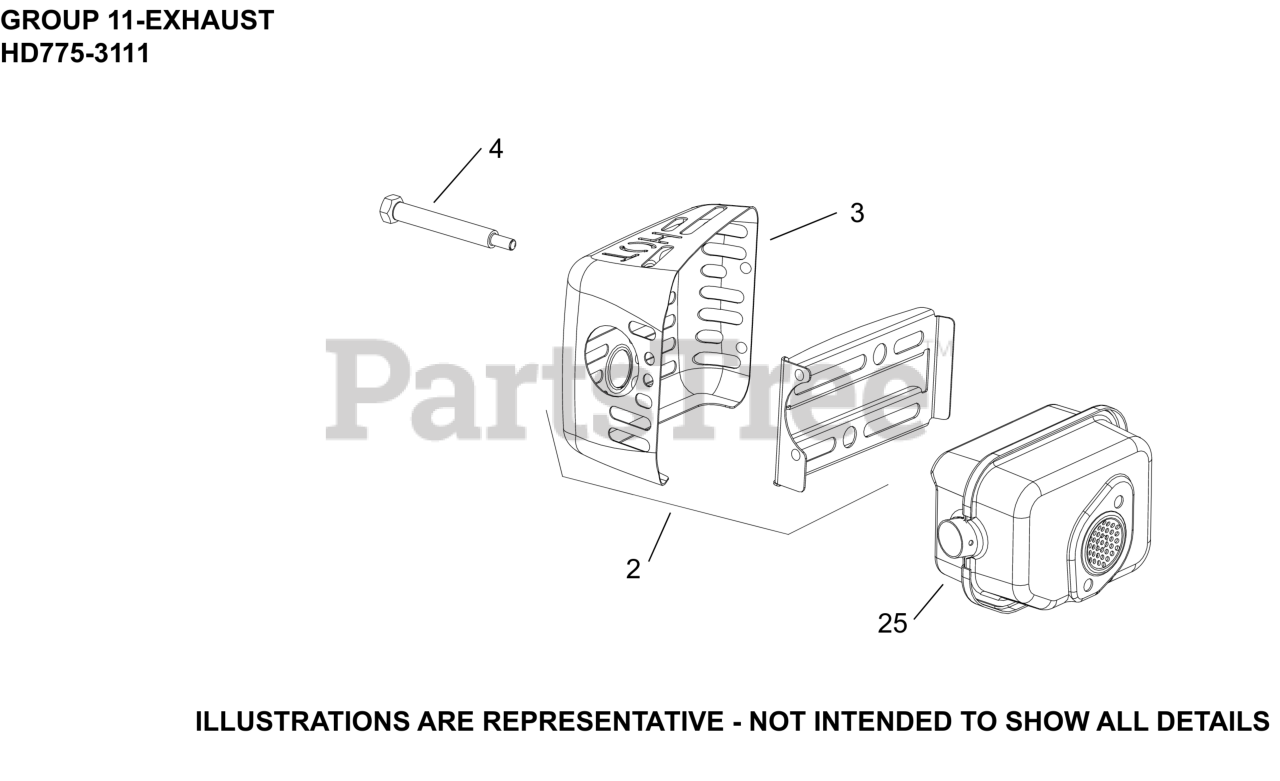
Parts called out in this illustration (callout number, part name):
2	GUARD, MUFFLER ASSEMBLY
3	GUARD, MUFFLER - DISCONTINUED
4	SCREW, SHOULDER
25	MUFFLER, ASSEMBLY
